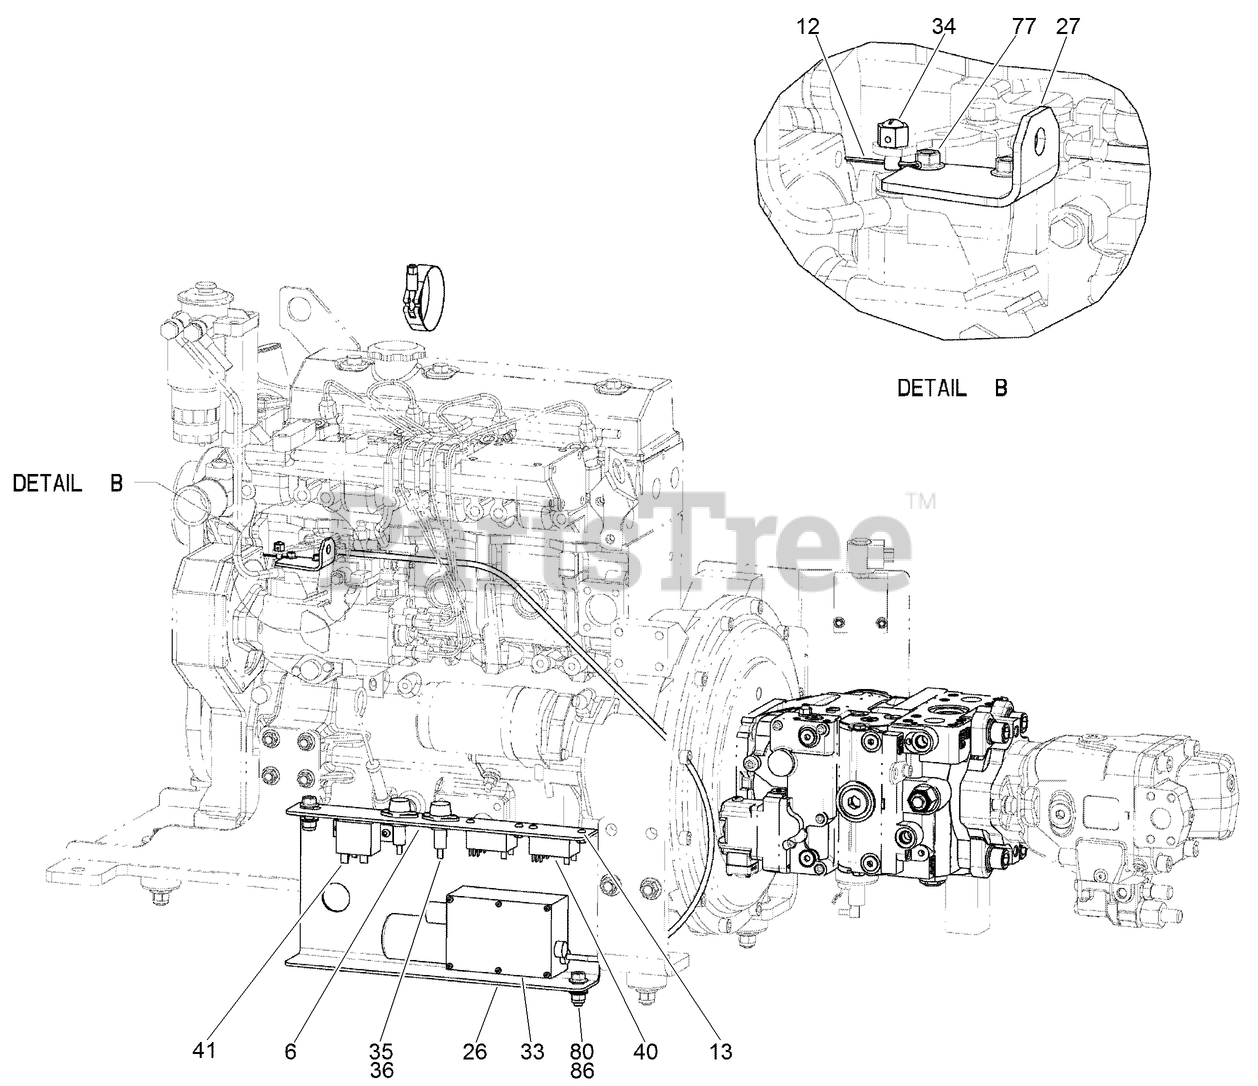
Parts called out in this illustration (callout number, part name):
6	NUT - Prev Trq # 10 GRB ZND Insert
12	PIN - Cotter .062 x 1.00 in ZN
13	SCREW - PHd Type 1 #10 - 24 x .500 CST ZND
26	RELAY BOARD
27	BRACKET - Throttle
33	ACTUATOR-THROTTLE
34	NUT - Cable Retaining
35	FUSE - Miget, 250 VDC, 30A
36	HOLDER - Fuse
40	RELAY - 2 Pole 12 VDC Panel Mount
41	RELAY - Power, 12 VDC
77	SCREW, METRIC FLANGE FULL - M6 x 16
80	NUT-FLANGE, NYLOCK
86	SCREW-HH
